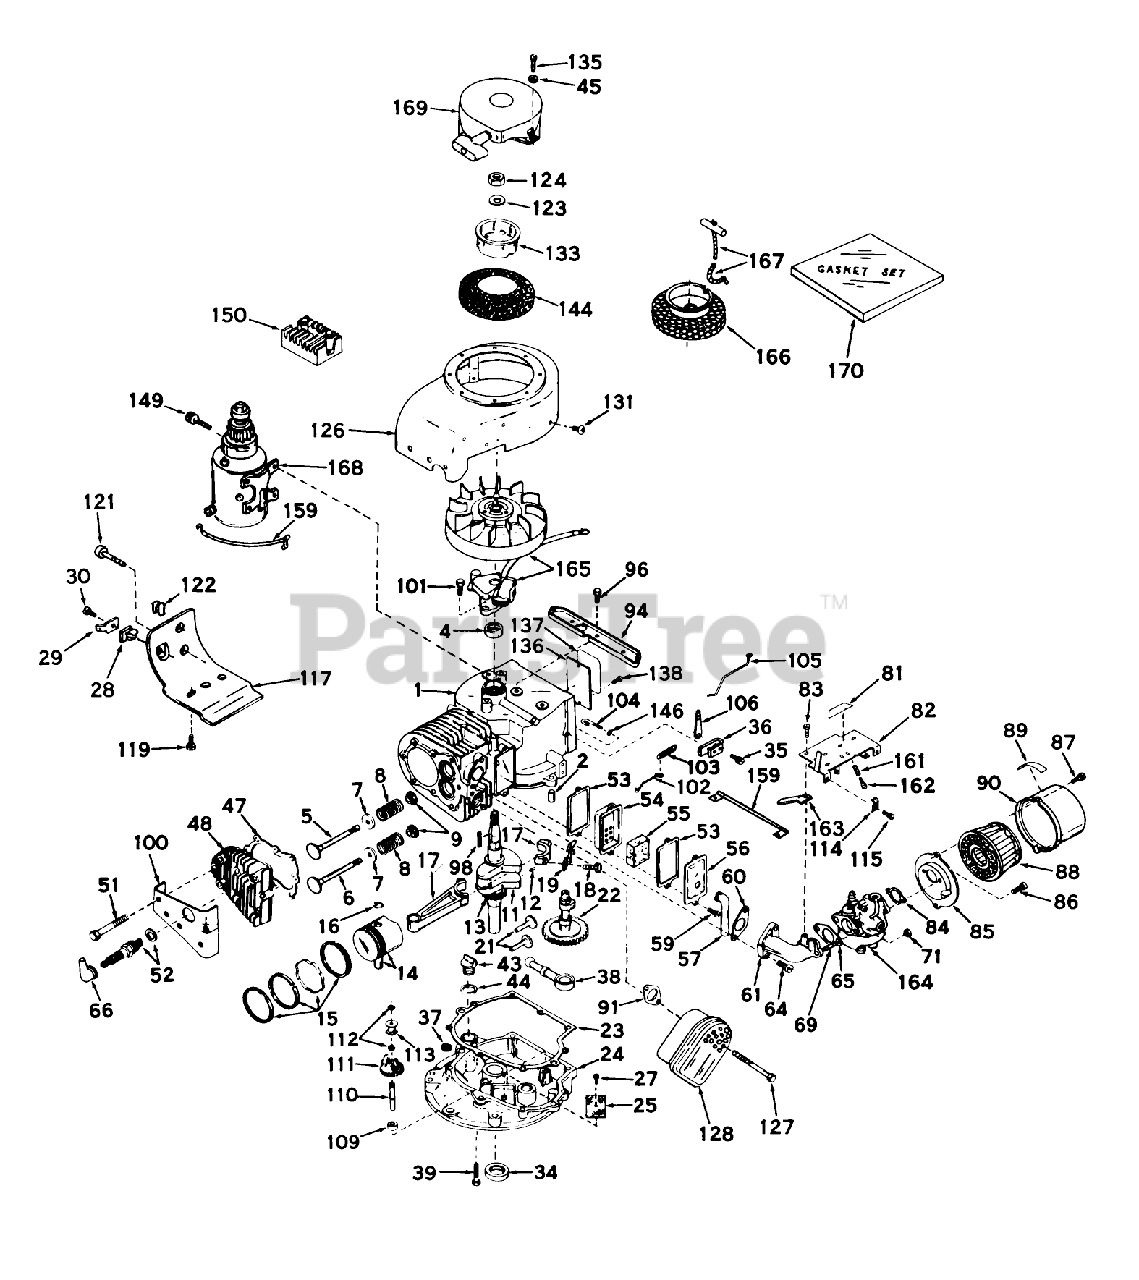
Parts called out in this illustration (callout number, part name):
1	Cylinder Assy. (Incl Nos. 2 4)
2	Pin-Dowel
4	Oil Seal
5	Valve, Intake (Standard)(Incl. No. 9)
5	Valve, Intake (1/32" oversize)(Incl. No. 9)
6	Valve, Exhaust (Standard)(Incl. No. 9)
6	Valve, Exhaust (1/32" oversize)(Incl. No. 9)
7	Cap-Spring, Valve
8	Spring-Valve
9	Keeper-Spring, Valve
11	Crankshaft Assy. (Incl. Nos. 12 13) (Model V70-125129)
11	Crankshaft Assy. (Incl. Nos. 12 13) (Model V70-125130)
12	Pin, Groove
13	Gear-Crankshaft
14	Piston Pin Assy. (Incl. 2 of No. 16)(Standard)
14	Piston Pin Assy. (Incl. 2 of No. 16)(.010 oversize)
14	Piston Pin Assy. (Incl. 2 of No. 16)(.020 oversize)
15	ORing
15	Ring Set (.010" OS)
15	Ring Set (.020" OS)
17	Rod Assy., Connecting (Incl. Nos. 18 19)
18	Screw, Hex Hd.
19	Plate, Lock
21	Lifter Valve
22	Screw
23	Gasket-Cover, Cylinder
24	Flange Assy., Mounting (Incl. Nos. 25, 27, 29, 34, 45 110)
25	Screen-Oil Filter
27	Screw
28	Grommet
29	Terminal
30	Screw
34	Seal-Oil
35	Screw
36	Clamp-Lever, Governor
37	Plug-Drain, Oil (SQH 1/4-18)
38	Pump, Oil
39	Screw (1/4-20 x 1-1/4)
43	Plug-Fill, Oil
44	Gasket
45	Washer
47	Gasket-Cylinder Head
48	Head, Cylinder
51	Screw
52	SPARK PLUG
53	Gasket-Breather
54	Body-Breather
55	Element-Breather
56	Cover-Valve
57	Tube-Breather
59	Screw
60	Gasket-Intake
61	Pipe-Intake
64	Screw (T-30, 5/16-18x1-3/32)
65	Gasket
66	51005 GIL.ROTARY TI
69	Stud
71	Nut and Lock Washer (1/4-28)
81	Decal
81	Decal, Speed control
82	Control Assy., Speed
83	Screw (10-24 x 9/16)
84	Gasket
85	Bracket
86	Screw (10-32 x 1/2)
87	Screw
88	Element
89	Decal
90	Body
91	Gasket Exhaust
94	Bracket, Blower Housing (Incl. Nos. 131)
96	Screw (1/4-20x19/32)
98	Key-Flywheel
100	Cover, Cylinder head
101	Screw
101	Screw, Hex Hd. Cap, Sems
102	Link Governor Spring
103	Spring Governor
104	Rod, Governor (Incl. Nos. 146)
105	Link Governor
106	Lever-Governor
109	Spacer
110	Shaft, Governor
111	Governor Gear ASM
112	Ring-Retaining
113	Spool-Governor
114	Conduit
115	Screw (10-32 x 3/8)
117	Emnsion, Blower Housing
119	Screw
121	Screw
122	51004 GIL ROTARY TI
123	Washer
126	Housing, Blower
127	Screw
128	Muffler
131	Screw, Hex Hd.
133	Cup-Starter
135	Screw
136	IDENTIFICATION PLATE
137	480B GIL SNWTHWR O/
138	Stud
144	Screen, Air
146	Washer-Flat
149	Screw
150	Regulator, Rectifier
159	Wire, Ground
161	Spring-Compression
162	Screw
163	Clip
164	Carburetor
165	Magneto
165	Magneto, Alternator
166	Hub Screen, Rope Starter
167	Rope Assy., Starter
168	Motor, Starter
169	Starter, Rewind
170	Gasket Set
